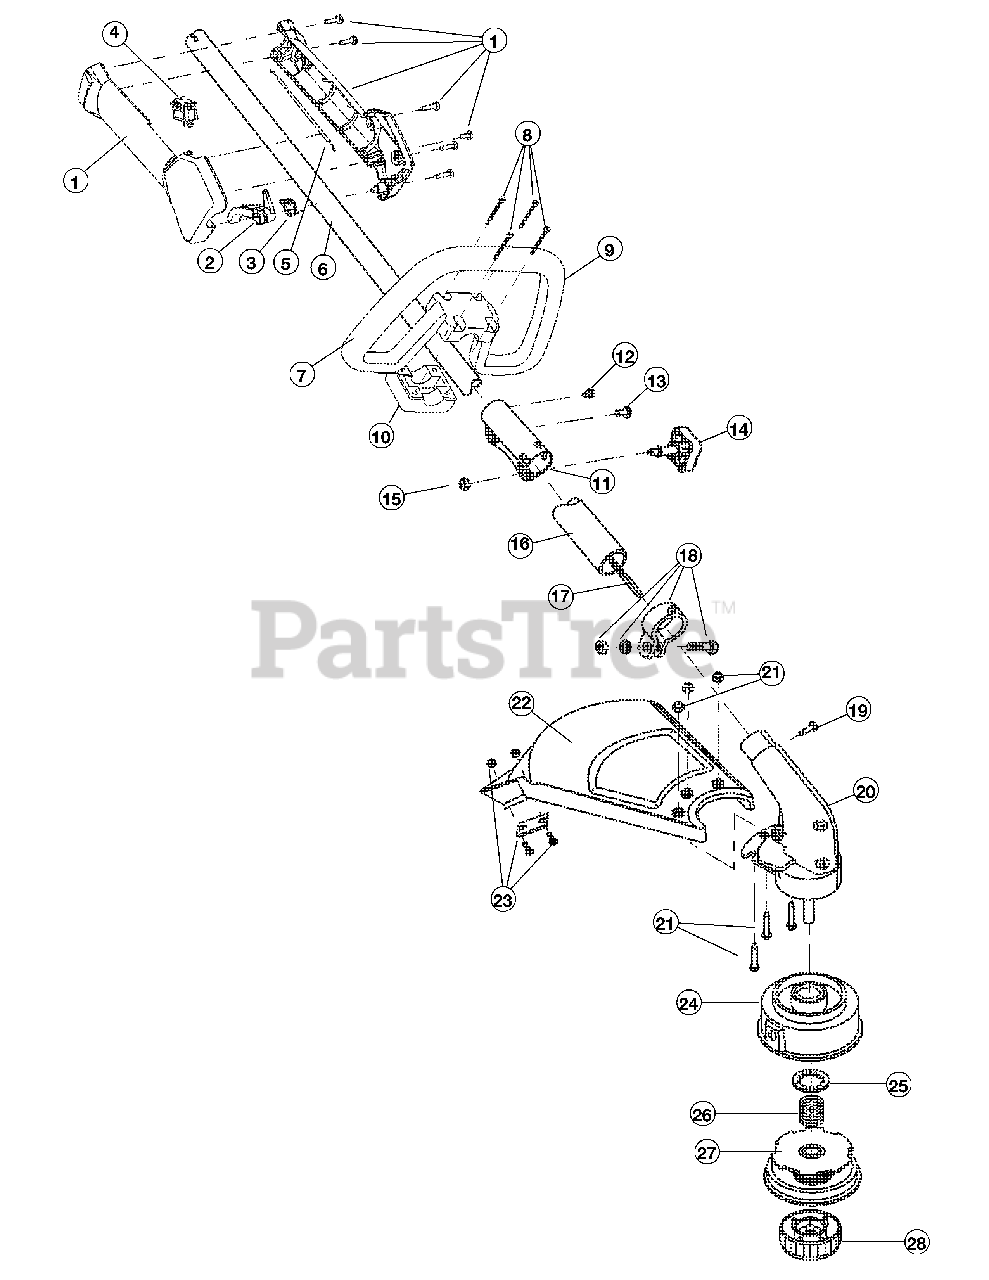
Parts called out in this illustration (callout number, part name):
1	Throttle Housing Assembly (includes 2-4)
2	Throttle Trigger
3	Throttle Trigger Spring
5	Throttle Cable Assembly
6	Upper Drive Shaft Housing Assembly
7	Deluxe D-Handle Assembly (includes 8-10)
9	Deluxe D-Handle
10	Bottom Clamp
11	Split Boom Coupler (includes 12-15)
14	Adjustment Knob
15	Knob Retaining Nut
16	Lower Drive Shaft Housing Assembly
17	Lower Flexible Drive Shaft
18	Lower Clamp Assembly (includes 19)
19	Anti-Rotation Screw
20	Gear Box Assembly
21	Shield Mounting Hardware
22	Shield Assembly (includes 23)
23	Blade Assembly
24	Outer Spool Assembly (includes 25)
27	Inner Reel
28	Bump Head Knob Assembly
